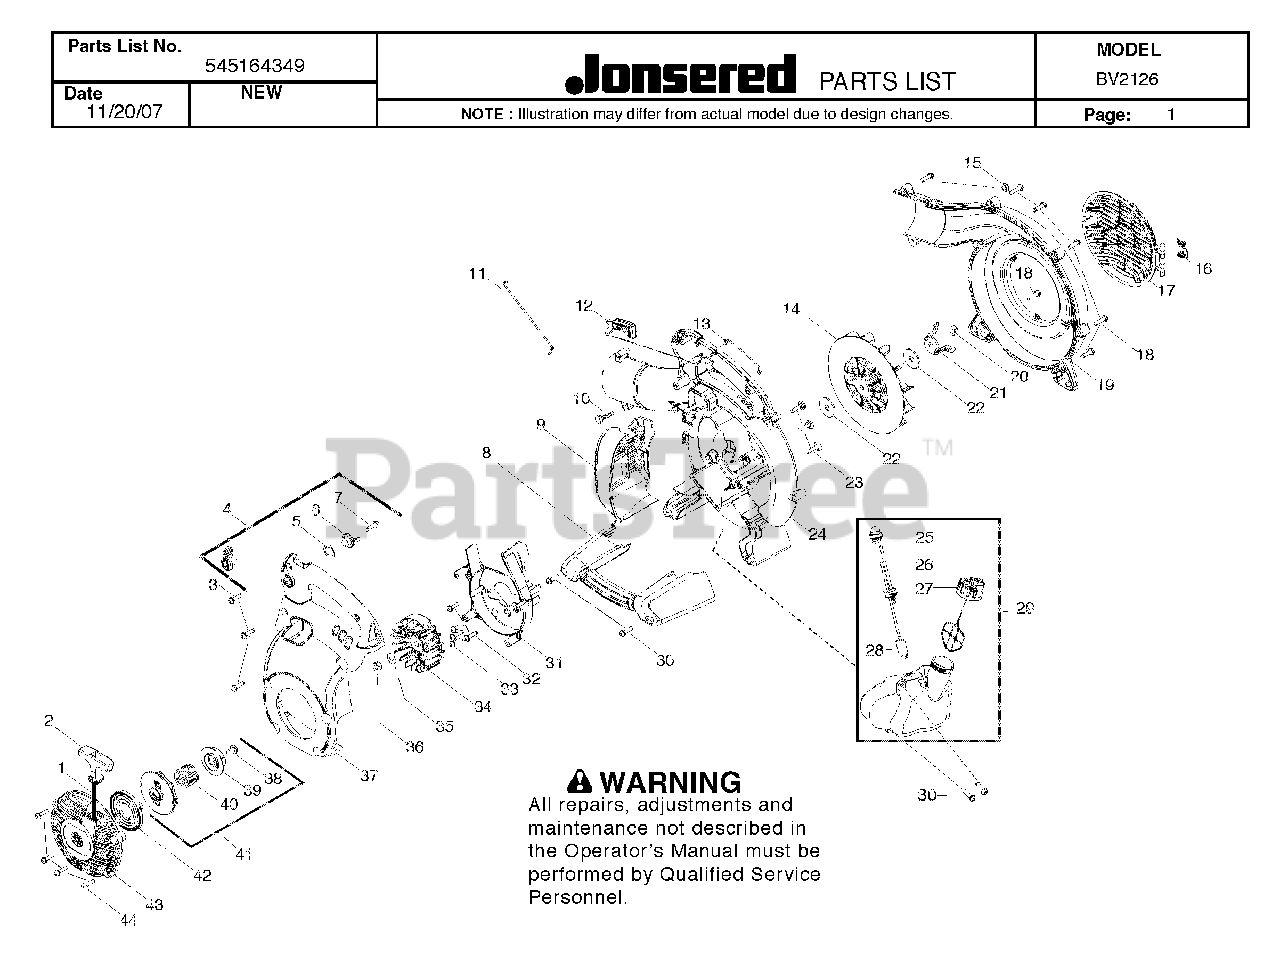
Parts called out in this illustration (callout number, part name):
2	HANDLE - STARTER
4	KIT - CRUIS CONTROL (5,6,7)
6	RATCHET CRUISE CONTROL
8	HANDLE - ASSIST
9	ASSY - MUFFLER GUARD
11	WIRE LINKAGE
12	TRIGGER - THROTTLE
13	WIRE, HANDLE GROUND
14	IMPELLER
16	SPRING, VAC DOOR
20	NUT, IMPELLER
22	WASHER IMPELLER
23	SCREW FUEL TANK RETAINER
25	AIR PURGE
26	KIT FUEL LINE GROMMET
27	ASSY - FUEL CAP W/RETAINER
28	FUEL PICK-UP ASSY
29	ASSY - FUEL TANK 26,27,28,29
31	SCROLL, FLYWHEEL
33	SCREW - SHROUD
34	ASSY, FLYWHEEL
35	WASHER FLAT
36	NUT-FLYWHEEL
40	SPRING EPS2
41	KIT - STARTER
42	SPRING STARTER
43	HOUSING - STARTER COVER
44	SCREW - SHROUD
